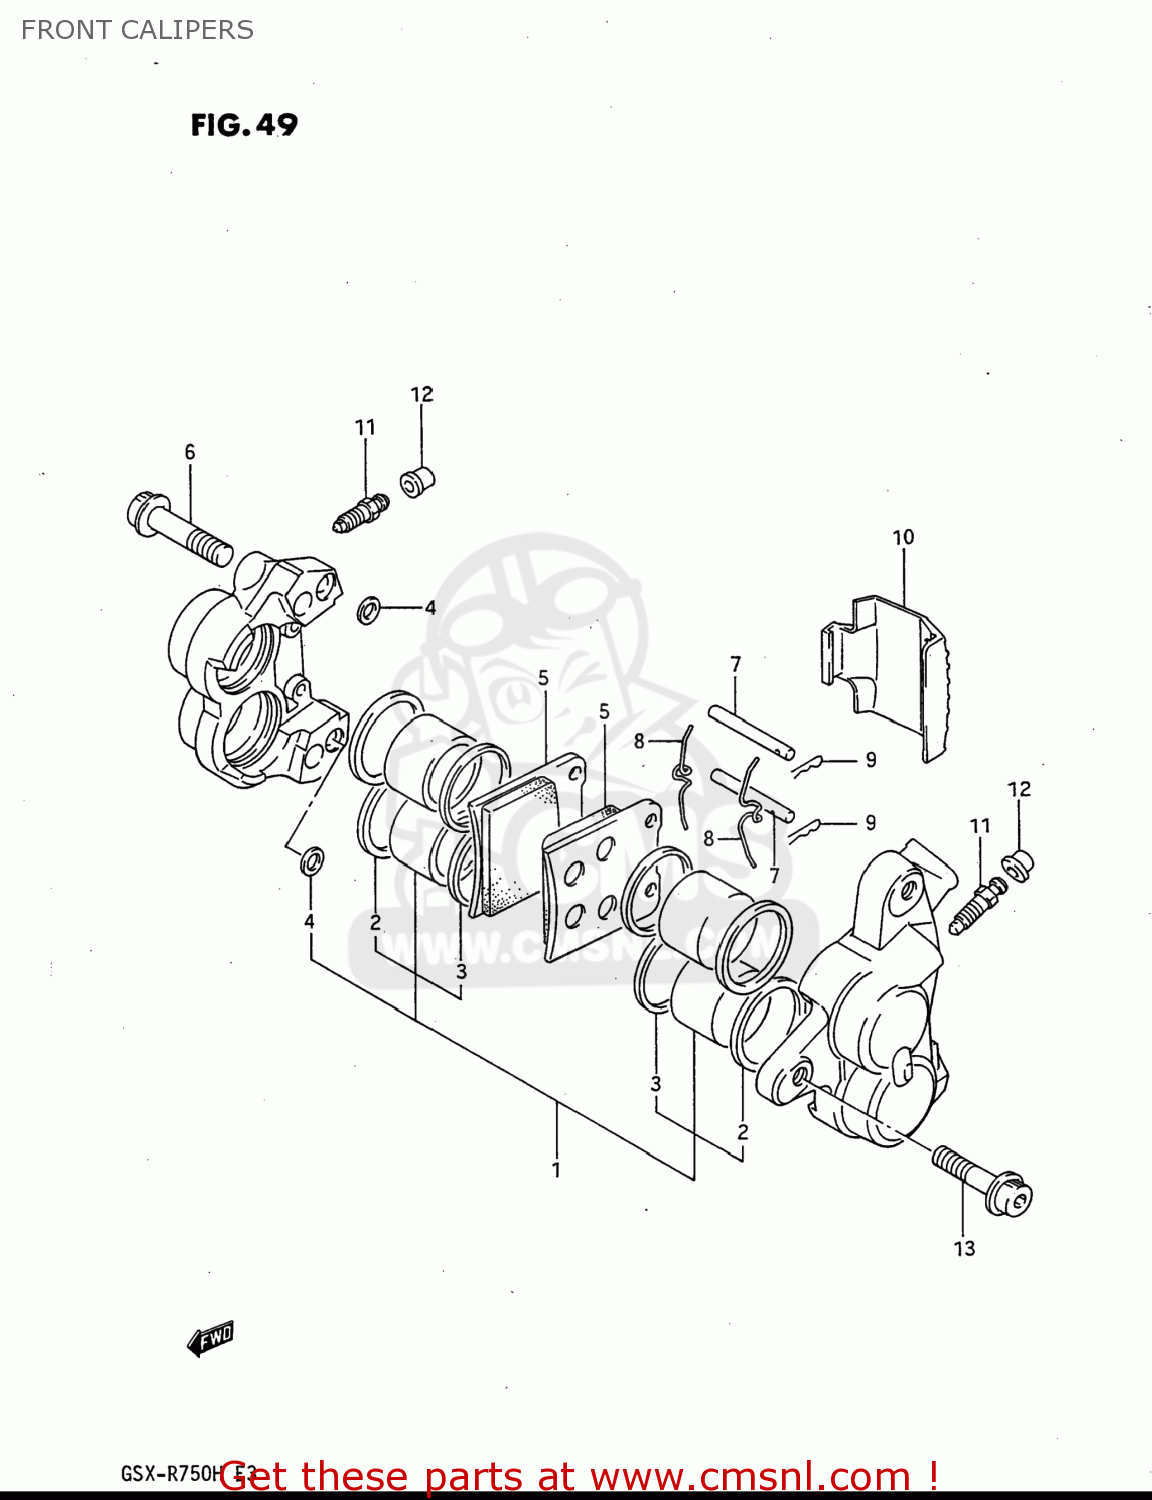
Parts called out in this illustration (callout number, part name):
1	PISTON SET
2	SEAL,PISTON
3	SEAL,WIPER
4	SEAL,JOINT
5	PAD,BRAKE (MCA)
6	BOLT,HOUSING
7	PIN,PAD
8	SPRING
9	CLIP,PAD PIN
10	COVER,CALIPER
11	BLEEDER
12	CAP,BREATHER
13	BOLT
